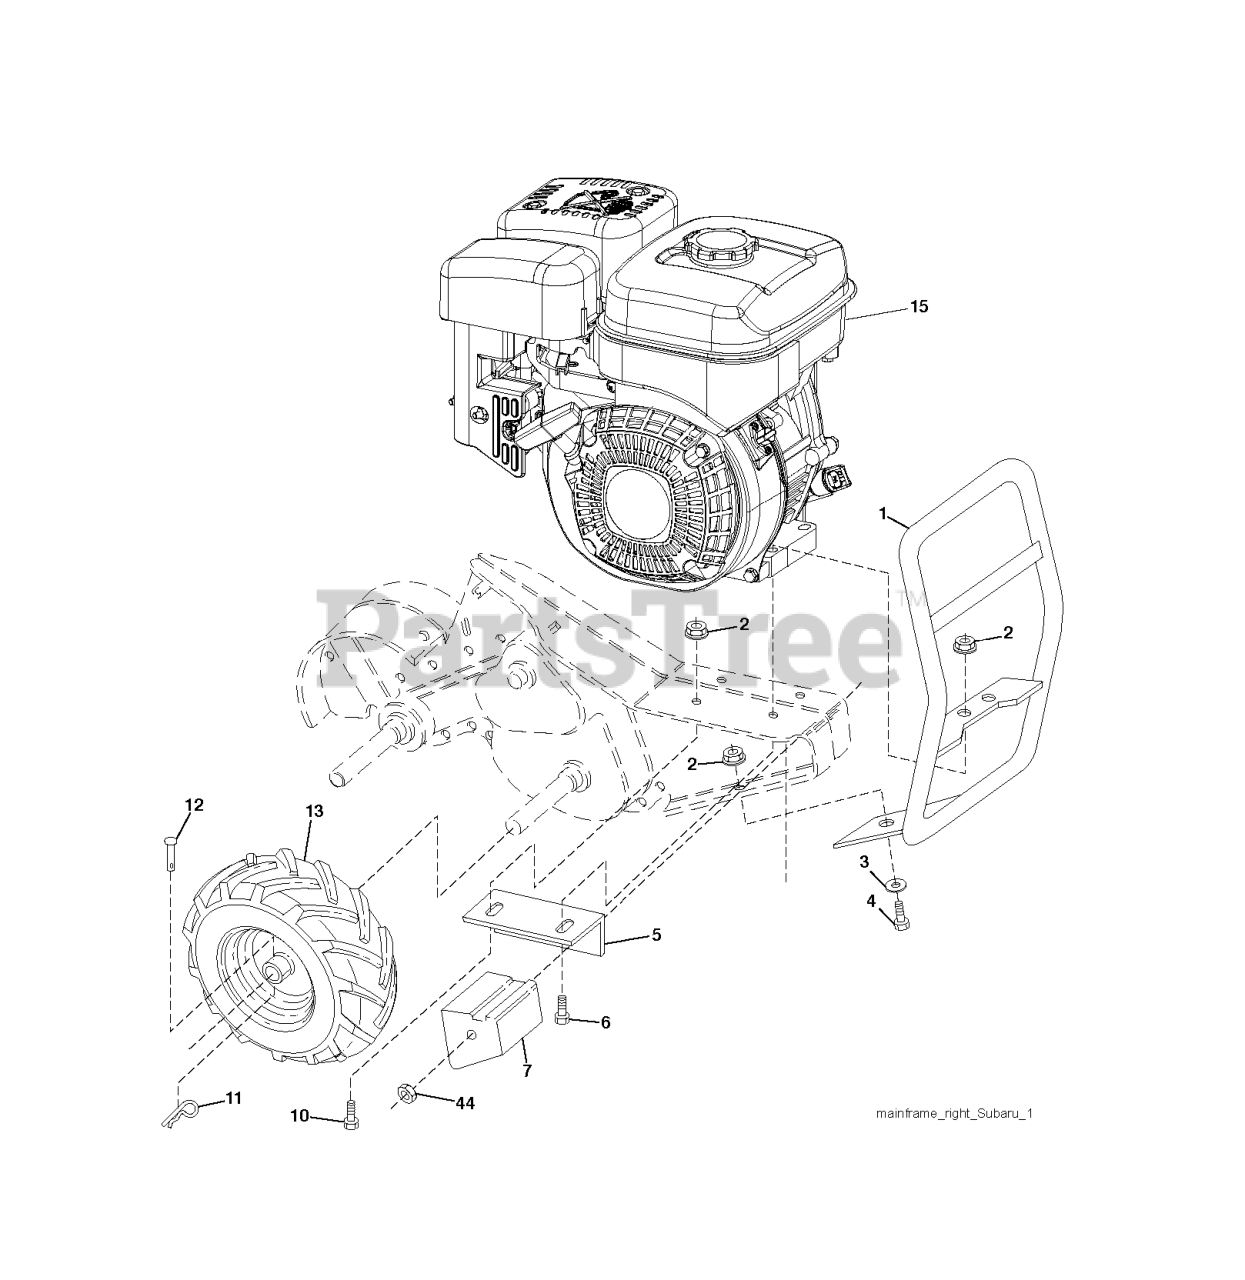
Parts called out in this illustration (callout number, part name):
1	RP.BUMPER.ASM.TILLER.
2	LOCKNUT-FLANGE 5/16-18
3	WASHER
4	BOLT
5	DNO BRACKET RH CRT
6	BOLT, HEX 5/16-18X1-3/4
7	COUNTERWEIGHT, RH
10	BOLT
11	RETAINER M
12	RIVET,DRILLED
13	TIRE.13X5-6.CHEVRON.TILLER
